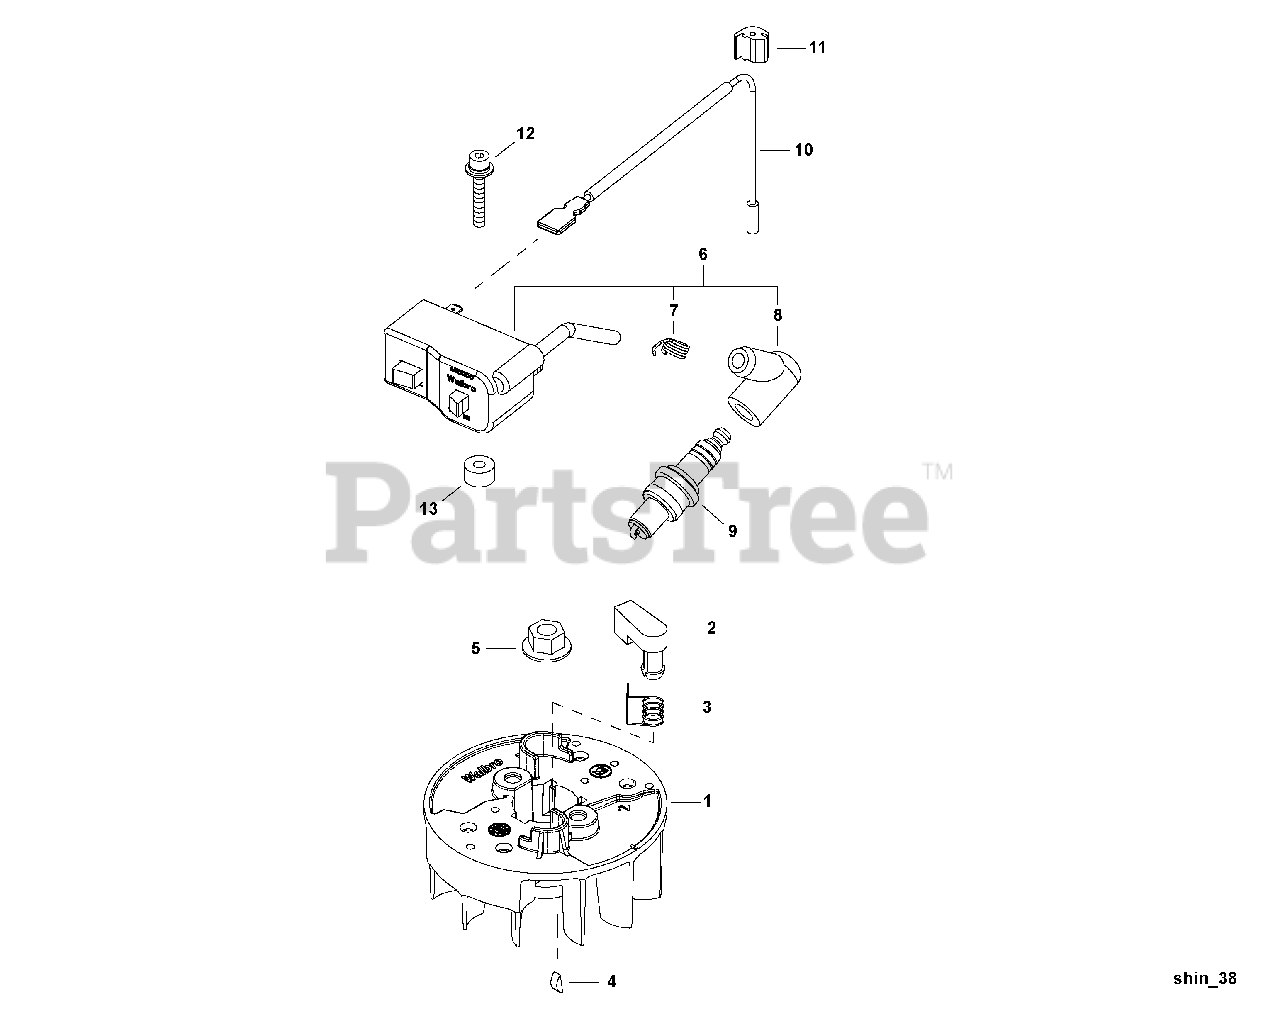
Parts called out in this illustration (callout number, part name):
1	FLYWHEEL
2	PAWL, STARTER
4	KEY - 3X10
5	NUT - 8
6	COIL, IGNITION
7	TERMINAL, SPARK PLUG CAP
8	CAP, SPARK PLUG
9	SPARK PLUG -- CMR-5H
10	LEAD - IGNITION
11	GROMMET
12	SCREW - 4X26
13	INSULATOR
